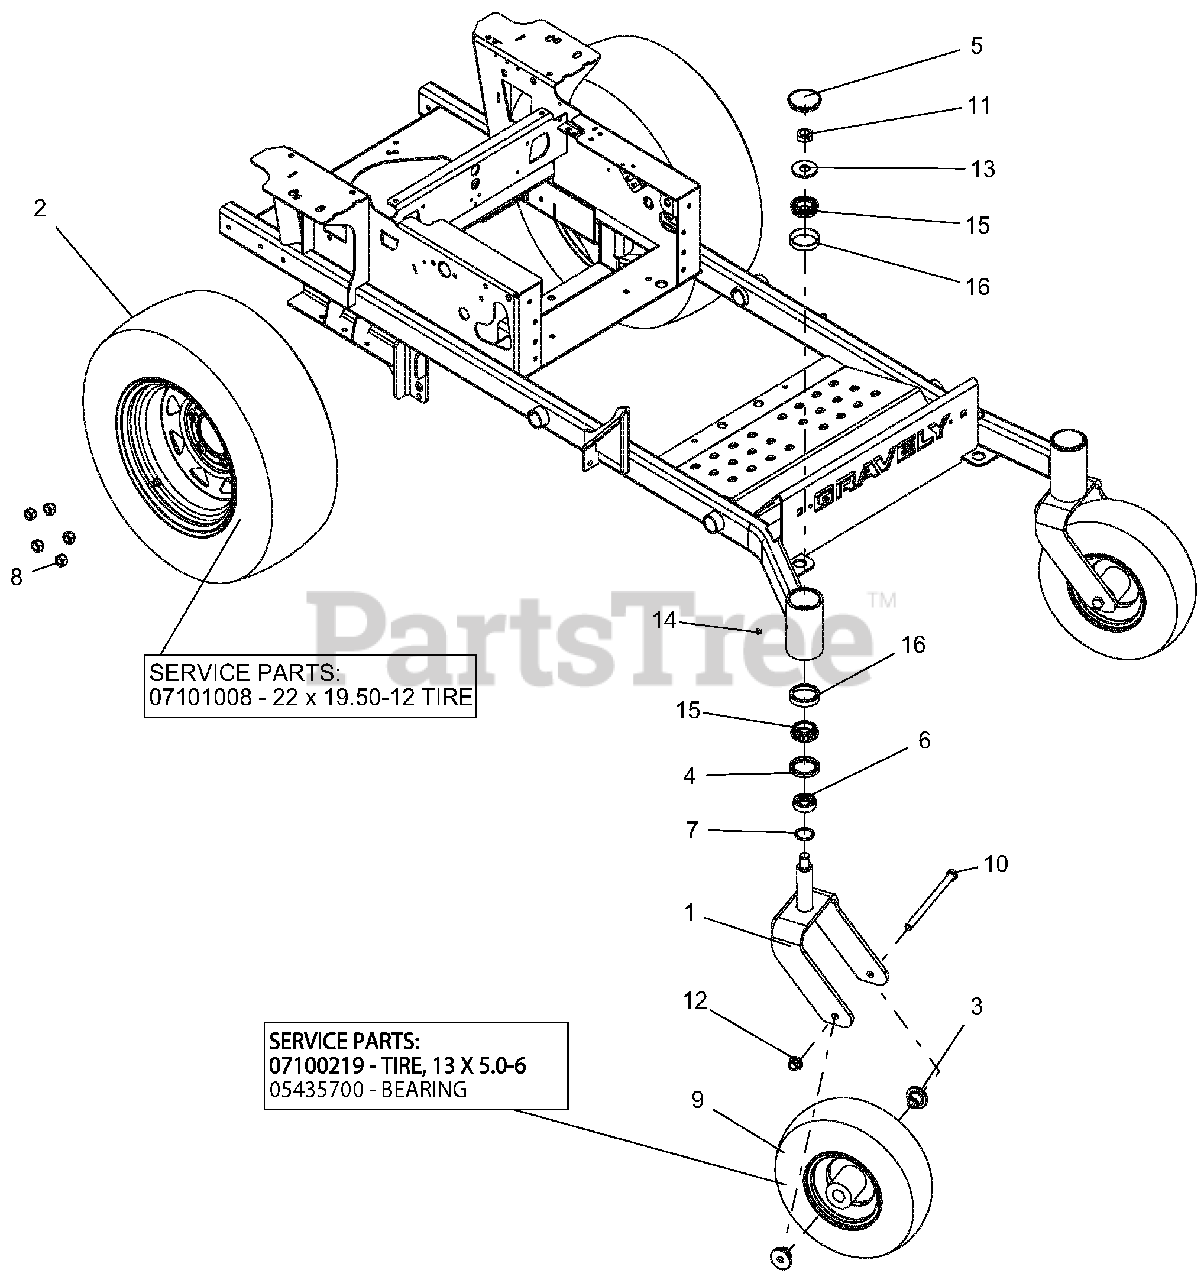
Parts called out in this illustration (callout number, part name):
1	WLDMT, CASTER FORK-RED
2	TIRE/WHEEL, ASSEMBLY 22X9.5-12
2	22 X 19.50-12 TIRE
3	SPACER, FRONT WHEEL
4	SEAL, OIL 1.75 X 2.332 X .312
5	CAP, DUST
6	SPCR, FRONT CASTER FORK
7	O-RING, .139 W X 1.234 ID
8	NUT, LUG .500-13
9	TIRE/WHEEL, ASM , 13X5-6
9	TIRE, 13 X 5.0-6
10	BLT-HEX .50-13X7.50 GR5 YWZC
11	@NUT-LK-CTR-JAM .75-16 YWZC
12	NUT-LK-NYL-FLG .50-13 YWZC
13	WSHR-FL-STL.812X2.00X.148YWZC
14	PLUG, .250-28 X .185 HEX HEAD
15	BRG, CONE 1.25 X .66
16	BRG, CUP 2.328X.465
